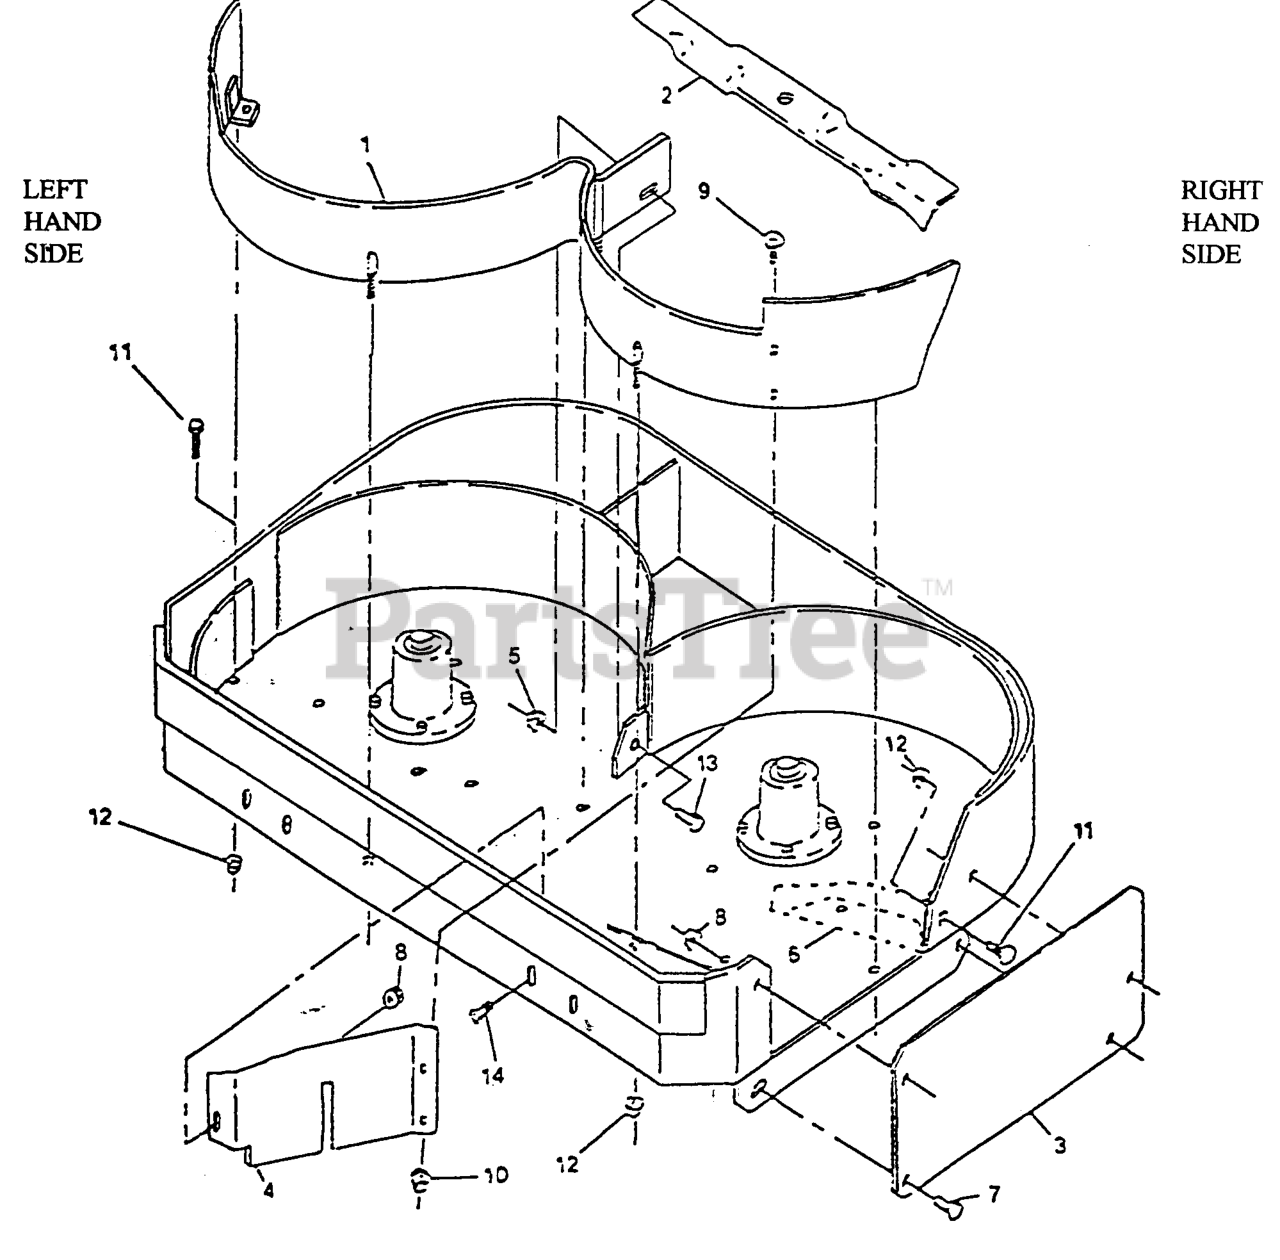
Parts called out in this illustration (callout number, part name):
1	BAFFLE-FRONT
3	PLATE-COVER
6	BAFFLE-DOGLEG
9	BOLT-CARR
